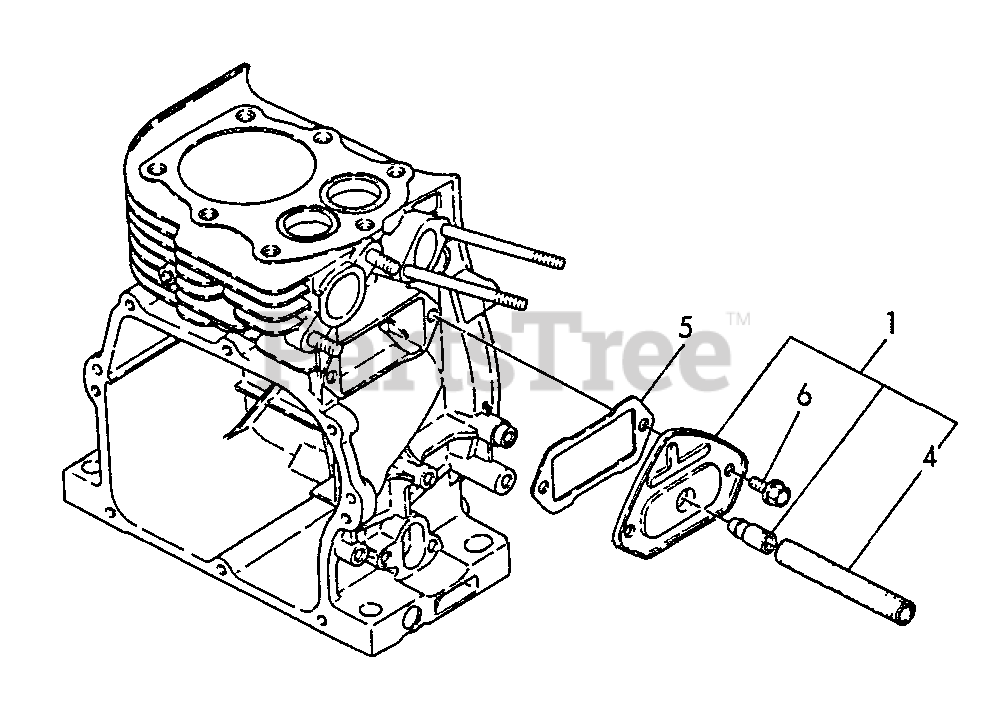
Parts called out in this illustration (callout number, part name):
1	BREATHER ASSY
4	PIPE, BREATHER
5	GASKET
6	BOLT - 6×8 -- PLATED
